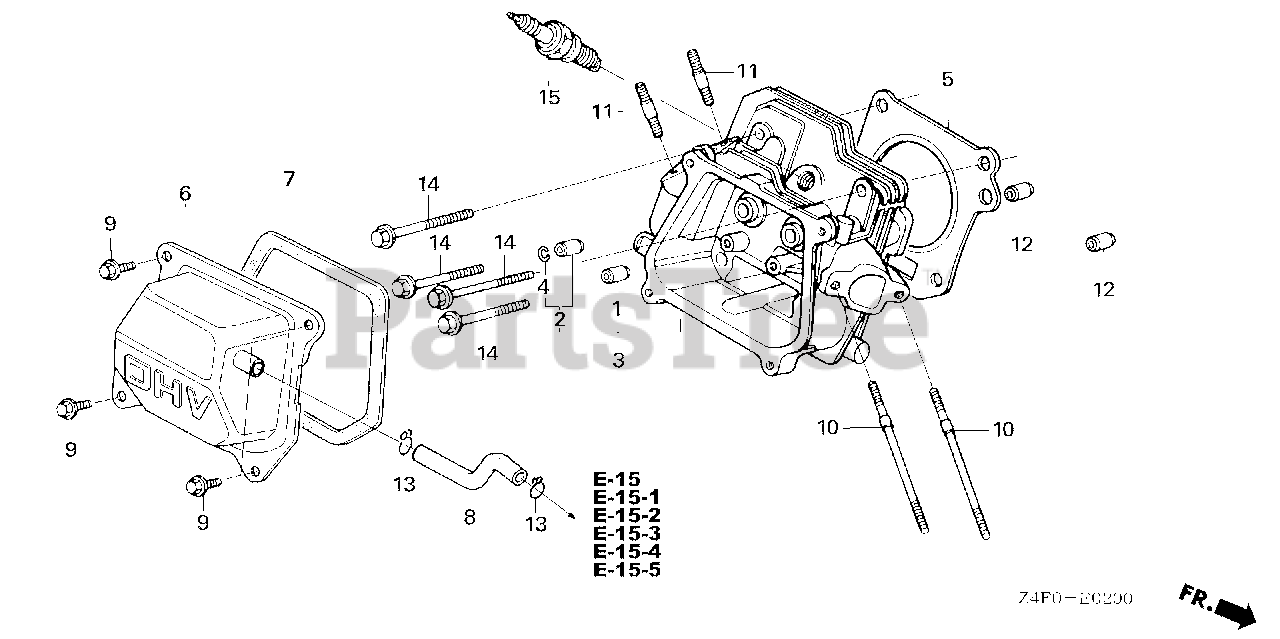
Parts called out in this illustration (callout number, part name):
1	GUIDE, VALVE (OVER SIZE)
2	GUIDE, EX. VALVE (OVER SIZE)
3	CYLINDER HEAD
4	CLIP, VALVE GUIDE
5	GASKET, CYLINDER HEAD
6	COVER, HEAD
7	GASKET, HEAD COVER
8	TUBE, BREATHER
9	BOLT, FLANGE (6X12) (CT200)
10	BOLT, STUD (6X112)
11	BOLT, STUD (8X32)
12	PIN, DOWEL (10X16)
14	BOLT, FLANGE (8X55)
15	SPARK PLUG (BPR5ES) (NGK)
15	SPARK PLUG (W16EPR-U) (DENSO)
15	SPARK PLUG (BPR6ES) (NGK)
15	SPARK PLUG (W20EPR-U) (DENSO)
